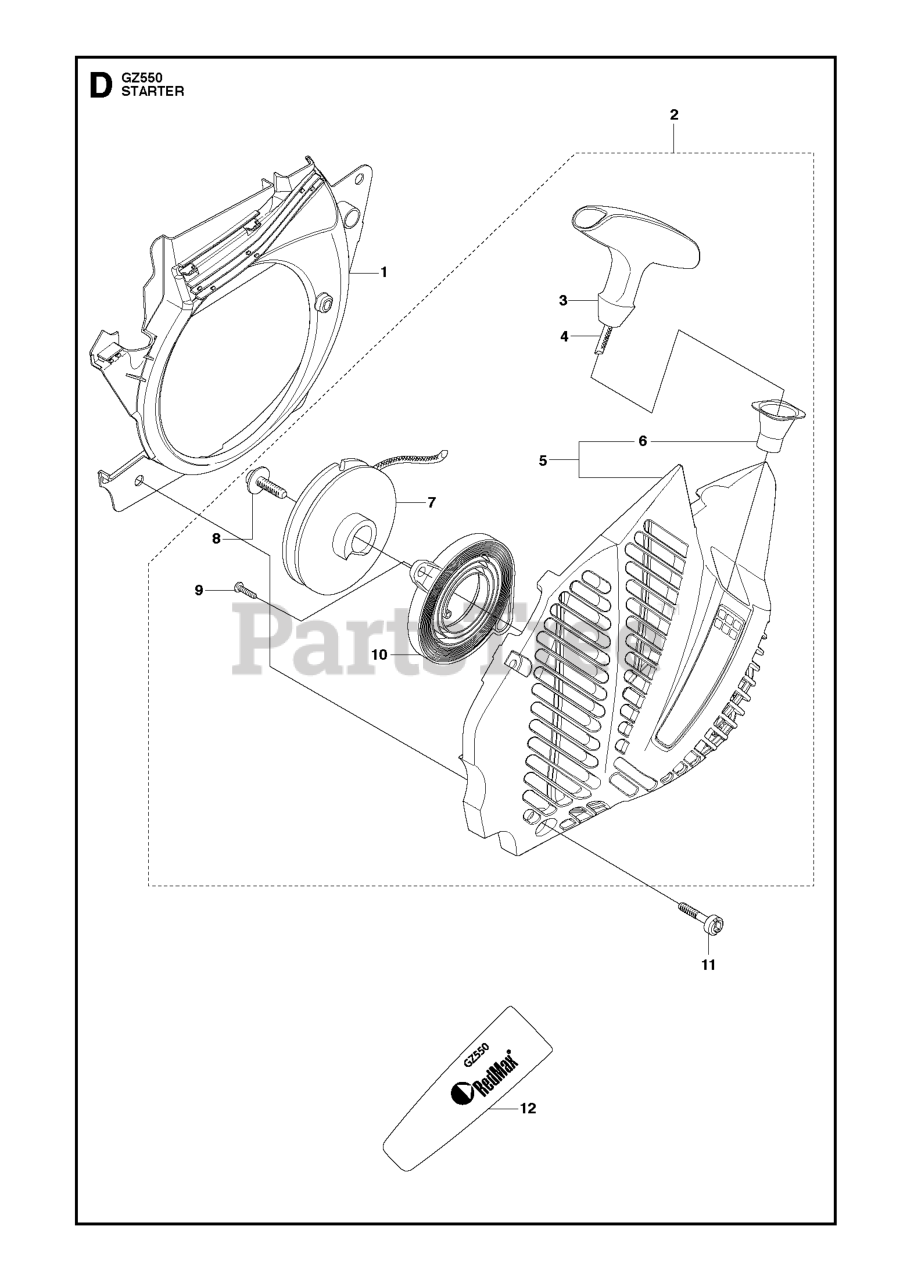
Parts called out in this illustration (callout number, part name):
1	AIR CONDUCTOR
2	STARTER ASSY
3	STARTER HANDLE
4	STARTER CORD
5	STARTER HOUSING
7	STARTER PULLEY
9	SCREW CCRPANT
10	RETURN SPRING
12	DECAL GZ550
